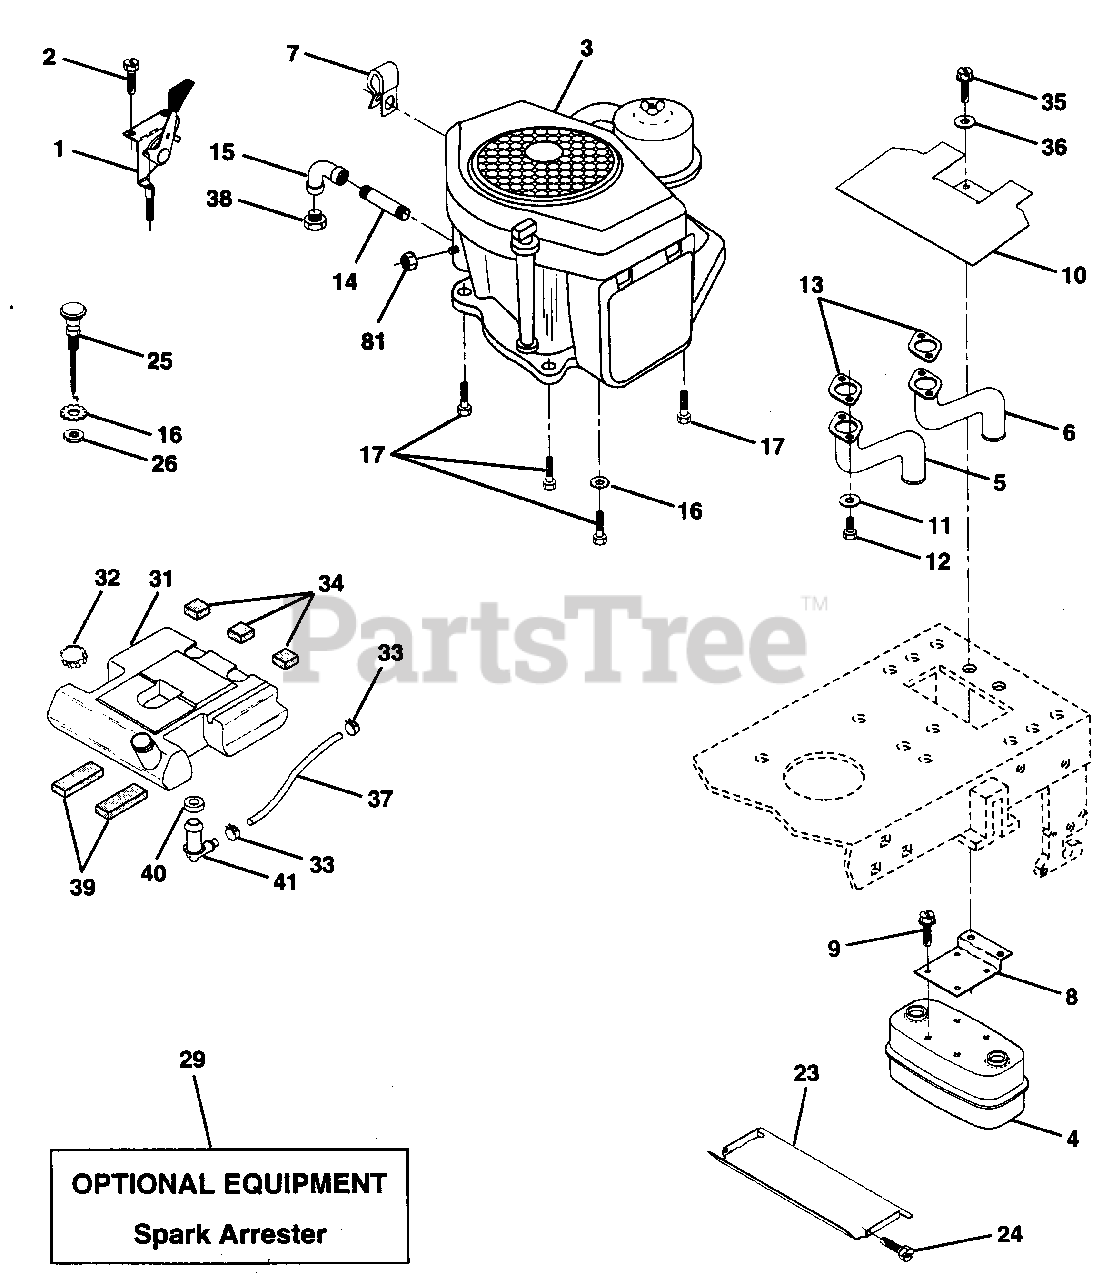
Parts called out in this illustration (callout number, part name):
1	Control Throt RH Blk Flg 41 60 (AYP part number)
2	Screw Hex Thd Cut 1/4-20x5/8 T (AYP part number)
4	Muffler VGT YT Dual Inlet (AYP part number)
5	Pipe Exhaust CV18/20 LH
6	Pipe Exhaust CV18/20 RH
7	Clip, Fuel Line (AYP part number)
8	Bracket Muffler Mounting (AYP part number)
9	Screw Hex Wsh Thd Cut 1/4-20 (AYP part number)
10	Shield Heat Muffler CV18/20 (AYP part number)
11	Washer Lock Hvy Hlcl 1/4 (Order from Engine Manufacturer) (AYP part number)
12	Bolt, Fin Hex 1/4-20 x 3/4 (Order from Engine Manufacturer) (AYP part number)
14	Nipple Pipe 3/8 Npt X 4-1/2" (AYP part number)
15	Elbow Std 90 Degree 3/8-18 Npt (AYP part number)
16	Washer Lock Ext Tooth 3/8 (AYP part number)
17	Screw Thdrol 3/8-16 x 1-1/2 (AYP part number)
23	Shield Heat Browning LT/YT (AYP part number)
24	Screw Tap Hex #10-24unc X 1/2 (AYP part number)
25	Choke Control (AYP part number)
26	Nut, Fin Hex 3/8-24 Unf (AYP part number)
29	Kit Spark Arrestor (Flat Scrn) (AYP part number)
31	Tank Fuel 3 50 Rear (AYP part number)
32	Cap Asm Fuel W/sym Vented (AYP part number)
33	Clamp Hose Blk (AYP part number)
34	Pad, Spacer (AYP part number)
35	Screw Thdrol 5/16-18 x 3/4
36	Washer 13/32 x 1-1/4 x 12 Ga. (AYP part number)
37	Line Fuel 54" (AYP part number)
39	Pad, Idler (AYP part number)
40	Bushing (AYP part number)
41	Stem Tank Fuel (AYP part number)
81	Nut Keps Hex 1/4-20 Unc (AYP part number)
